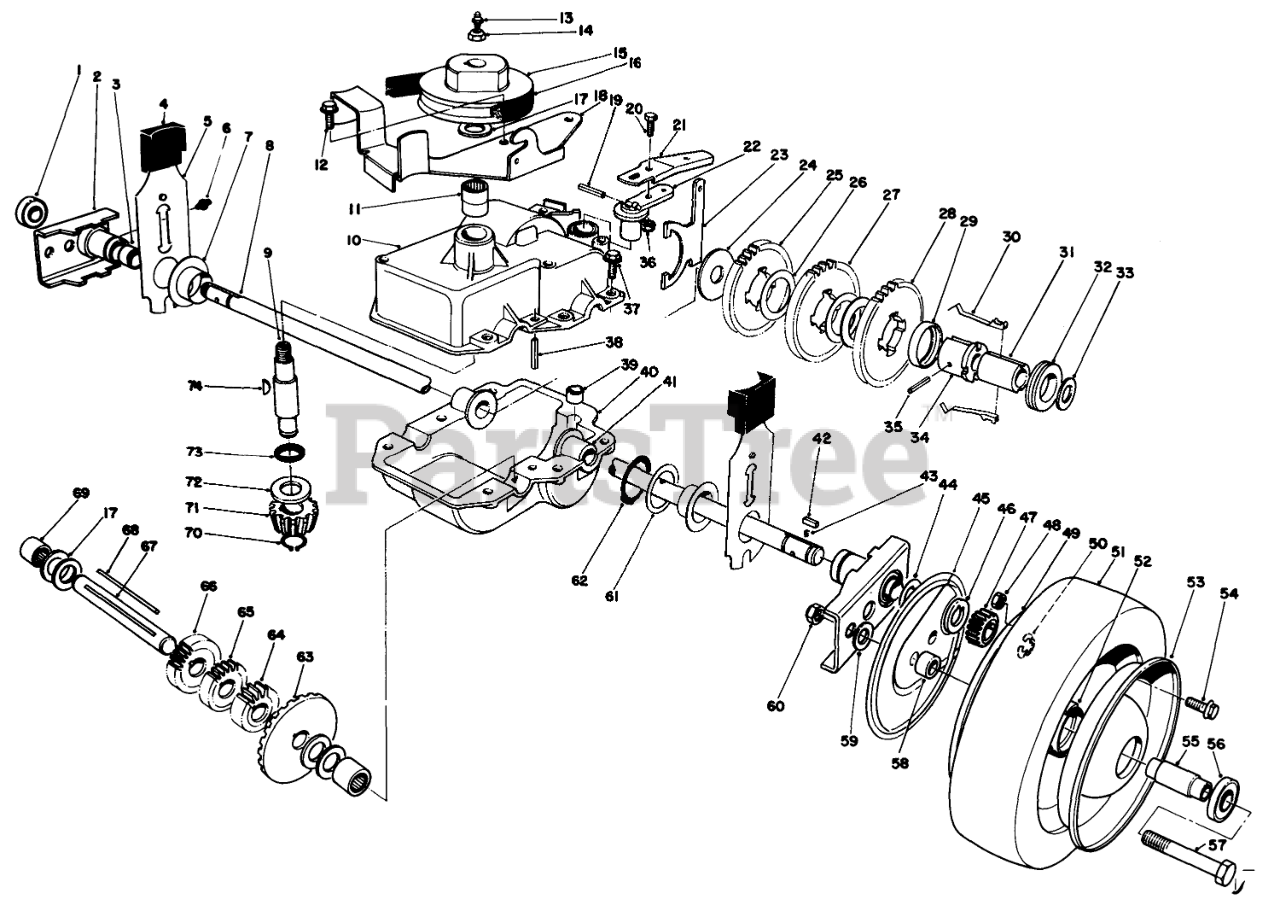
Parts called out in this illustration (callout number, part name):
1	BEARING-WHEEL
2	Pivot Arm Assembly (Incl. Ref. #1, 3 & 6)
3	BUSHING
4	KNOB-ARM
5	REAR SPRING ARM ASM
6	FITTING-GREASE
7	CAP-END
8	Shaft-Output
9	Shaft Input
10	Upper Case Assembly (Incl. Ref. #11 & 73)
11	BEARING-NEEDLE
12	SCREW
13	FITTING-GREASE
14	NUT-HEX
15	PULLEY
16	V-BELT
17	WASHER-THRUST
18	Belt Guide Bracket
19	PIN-COIL
21	SHIFT LEVER COVER
22	LEVER-SHIFT
23	Shift Yoke
24	WASHER
25	GEAR-38T
26	WASHER
27	GEAR-42T
29	RETAINER-KEY
30	KEY-SHIFT
31	SLEEVE
32	COLLAR-SHIFT
33	WASHER-PLAIN
34	SLEEVE-GEAR
35	PIN-GROOVE
36	NUT-LOCK, NI
37	SCREW-HWHTF
38	ROLL PIN 3/16 X 1 IN
39	BUSHING-YOKE
40	Case-Lower
41	BUSHING
42	KEY RECTANGULAR
43	SPRING-COMPRESSION
44	WASHER-THRUST, OUTER
45	WHEEL COVER
46	WASHER-THRUST, OUTER
47	GEAR-PINION
48	NUT-LOCK, NI
49	Wheel-Half
50	RING-RETAINING
52	HUB-BEARING
53	Wheel-Half
54	SCREW-HHF
55	SPACER-BEARING
56	BEARING-WHEEL
57	SCREW-HH
58	SPACER-WHEEL
59	WASHER
60	NUT-LOCK, CONE
61	WASHER
62	RING-RETAINING
63	BEVEL GEAR
64	GEAR-12T
65	GEAR-14T
66	GEAR-18T
67	SHAFT-INTERMEDIATE
69	BEARING-NEEDLE, CLOSED
70	RING-RETAINING
71	PINION-BEVEL
72	WASHER-THRUST
74	KEY-WOODRUFF
